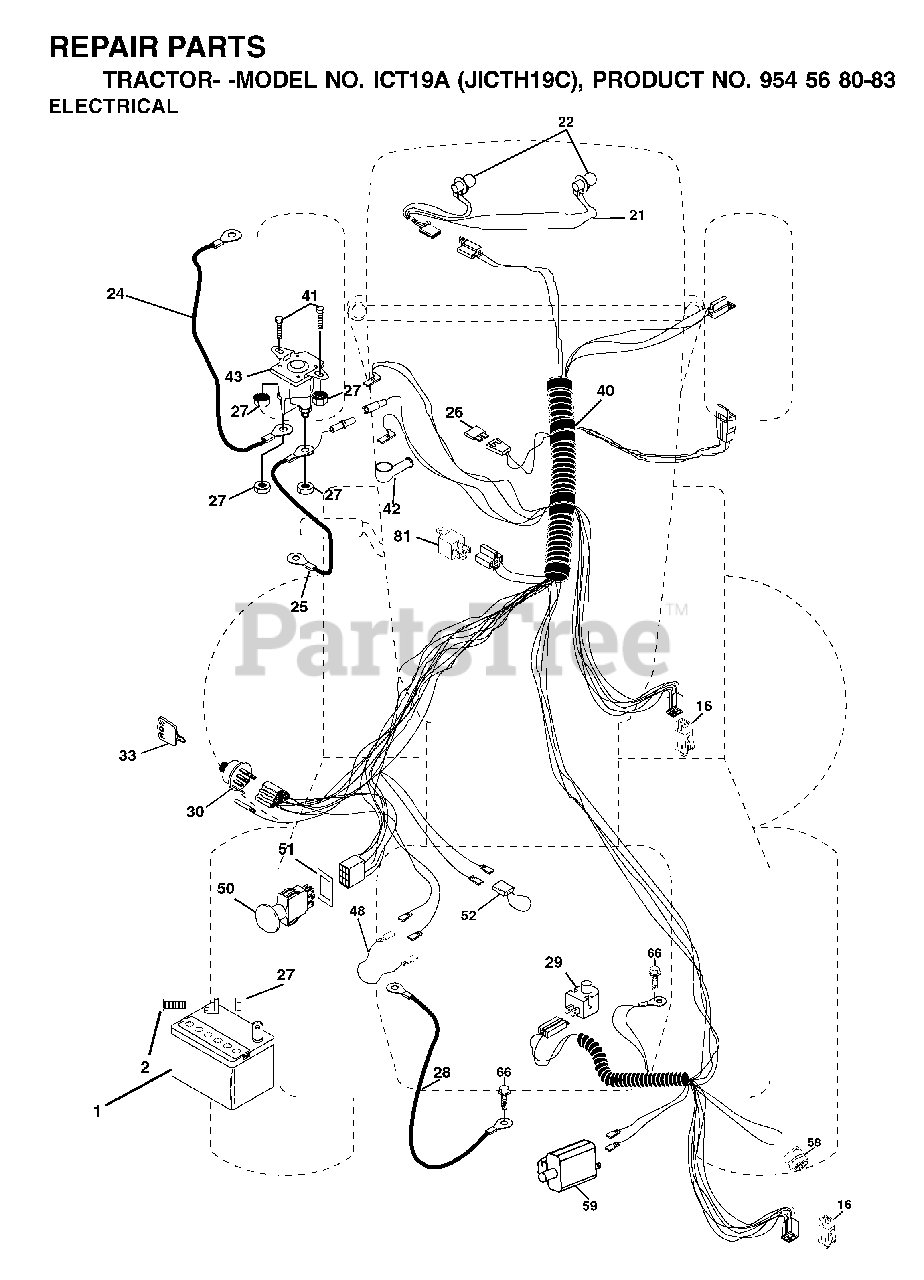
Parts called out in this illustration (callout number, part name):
1	BATTERY 12V .35 AMP
16	SWITCH INTERLOOK PUSH-IN
21	HARNESS.W/LIGHT SOCKET
22	LIGHTBULB
24	BATTERY CABLE GT
25	CABLE BATTERY
26	FUSE 20AMP
27	NUT
28	CABLE GROUND
29	PLUNGER SWITCH (COLOR:OLIVE)
30	IGNITION SWITCH
33	KEY MLD GEN DELTA
42	TERMINAL COVER
43	SOLENOID
50	SWITCH.PTO.8.TERMINAL.
51	RETAINING RING
52	WIRE PROTECTION LOOP
58	BUZZER
81	RELAY.ASSY.T
